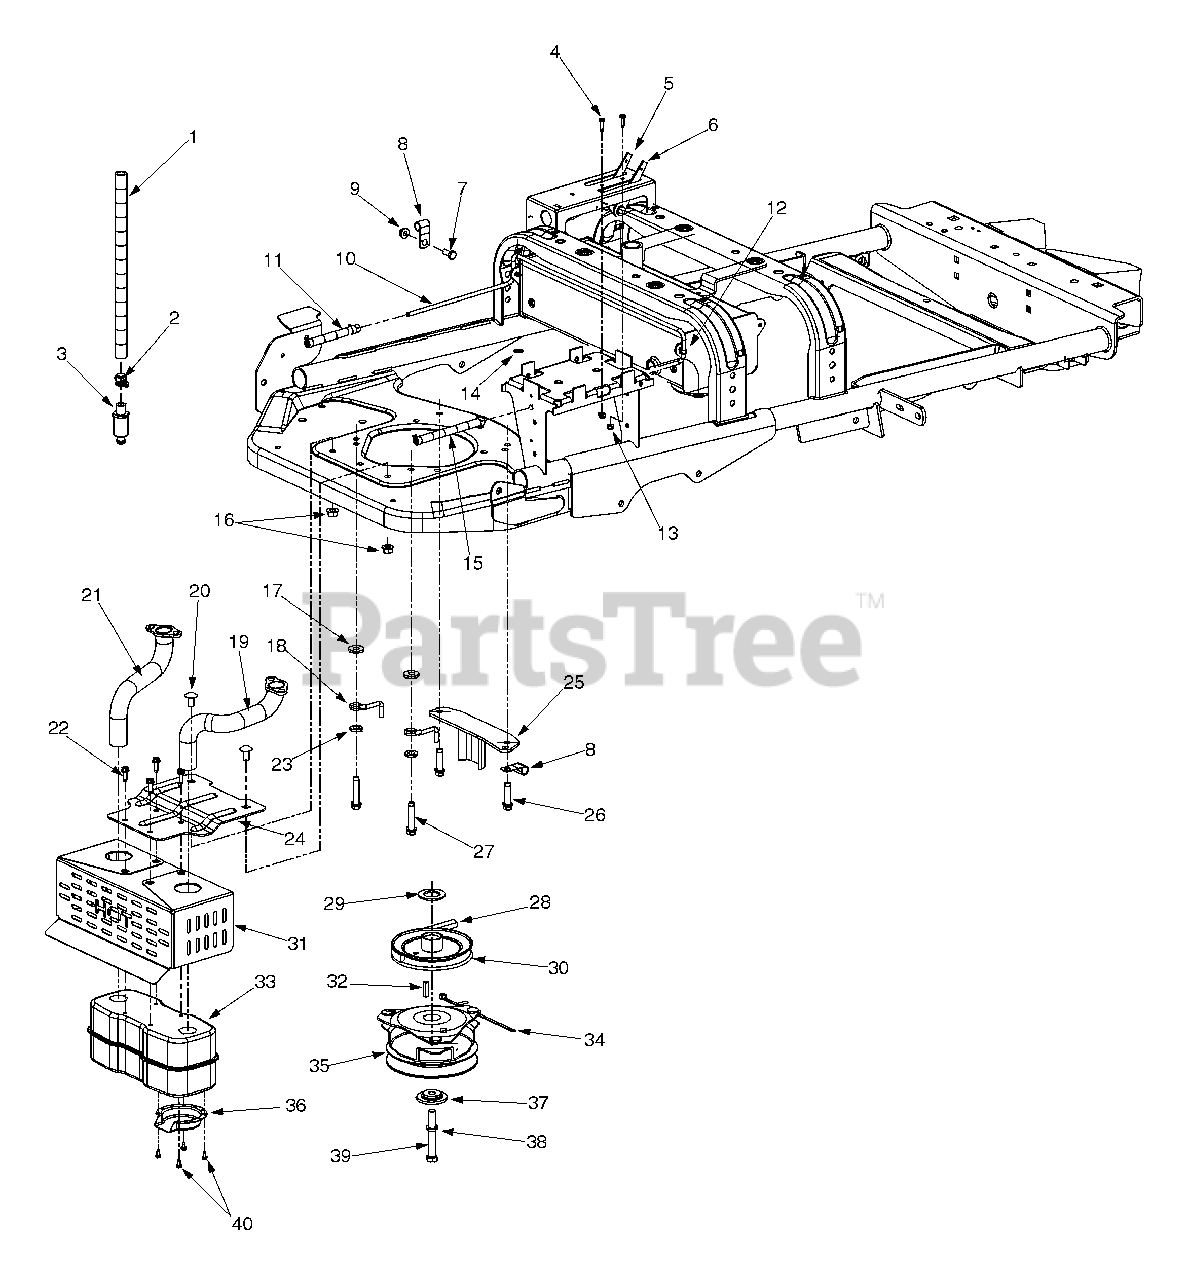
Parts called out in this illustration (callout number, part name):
1	Oil Drain Hose
2	Oil Drain Cap
3	Oil Drain
4	Screw #10-24 x .750
5	Throttle Control Cable 40.5"
6	Choke Control Cable 38.0"
7	Hex Cap Screw 5/16-18 x .75
8	Cable Clip Heat Shield
9	Hex Lock Nut 5/16-18
10	Fuel Line
11	Hose Clamp
12	Retainer Clip
13	Lock Nut #10-24
14	Lock Washer 5/16
15	Fuel Line Hose
16	Flange Lock Nut 3/8-16
17	Flat Washer .385 ID x 1.0 OD
18	Rear Belt Retainer Rod
19	Exhaust Pipe LH
20	Carriage Bolt 3/8-16 x .75
21	Exhaust Pipe RH
22	Hex Washer Screw 1/4-20 x .75
23	Flat Washer .407 ID x .812 OD
24	Muffler Bracket
27	Hex Washer Screw 3/8-16 x 1.875
28	V-Belt
29	Flat Washer 1.0 ID x 1.75 OD
30	Drive Pulley
33	Duel Muffler
34	Cable Tie
35	Electric PTO Clutch
36	Muffler Deflector
37	Spacer Clutch
38	Lock Washer 7/16
39	Hex Cap Screw 7/16-20 x 3.25
40	Hex Washer Screw #8-32 x .375
